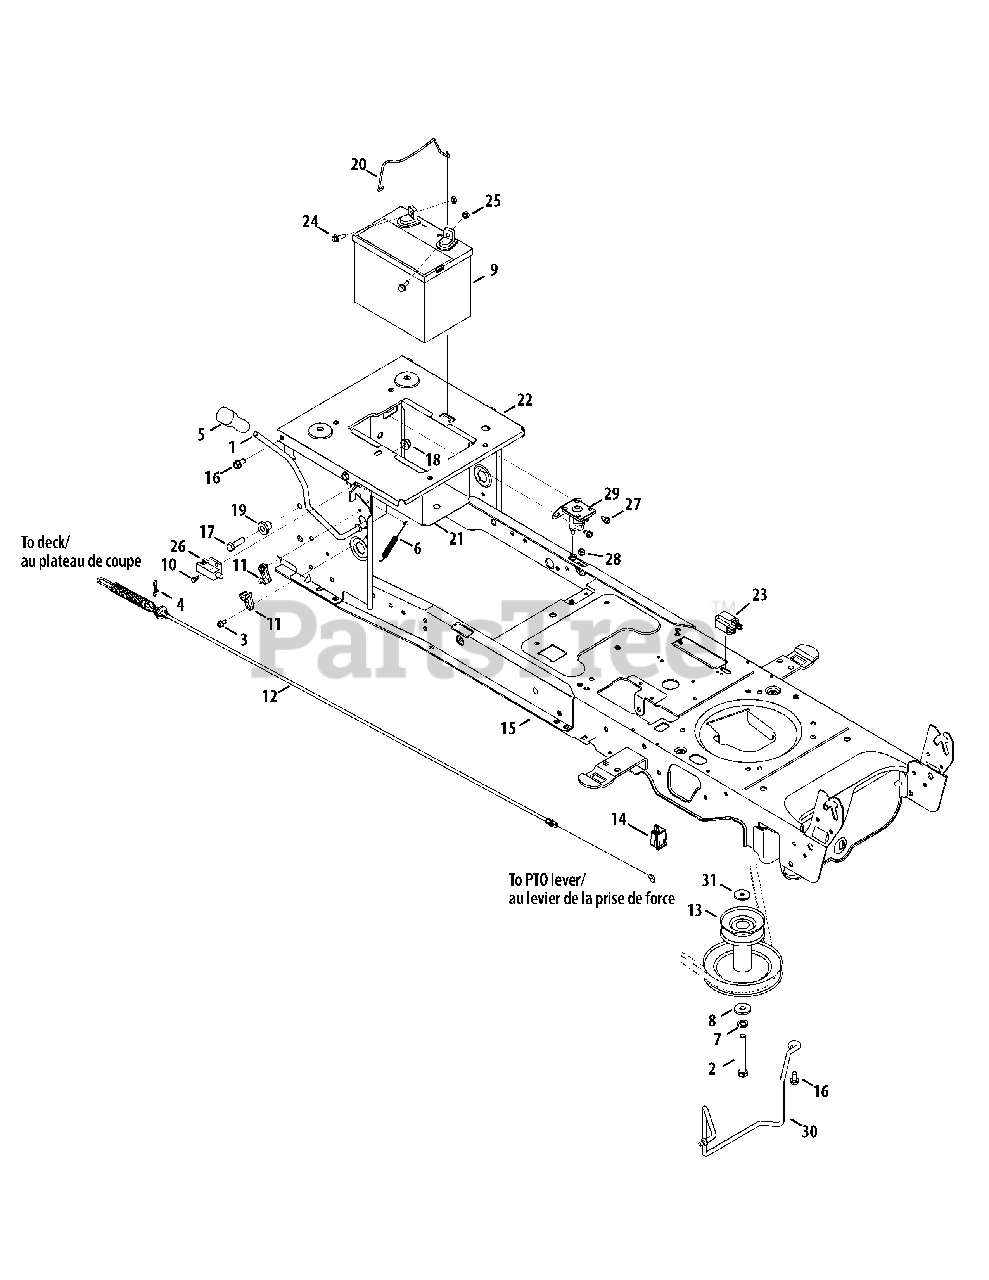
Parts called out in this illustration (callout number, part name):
1	Handle Ass’y , PTO
2	Hex Screw 7/16-20 x 3.5 Gr. 5
3	Hex Wash S-Tapp Screw 1/4-20 x .50
4	Bow-Tie Cotter Pin
5	Handle Grip 3/8
6	Extension Spring .38 Dia. x 5.6
7	Lockwasher 7/16 ID
8	Flat Washer .450 x 1.25 x .164
9	Battery 245 CCA (Dry)
10	Shoulder Screw #10-32 x .50
12	Deck Engagement Cable
13	Engine Pulley 3.39 x 6.12 Dia.
14	Switch, Plunger, snap mount
16	Hex Wash Hd. Tapp Screw. 5/16-18 x .75
17	Hex Bolt 3/8-16 x 1.25
18	Flange Lock-Nut 3/8-16 Gr. F Nylon
19	Shoulder Spacer .38 x 1.0 x .70
20	Battery Retainer Rod
23	Switch, 3-Pole, (NC-NO-NO)-Brake
24	Hex Hd. Flg. Screw. 1/4-20 x .75 Gr. 5
25	Sems Hex Nut 1/4-20
26	Switch, Interlock
27	Hex Wash HD Tapp Screw 1/4-20 x .375
28	Hex L-Flanged Nut 1/4-20 Gr. F Nylon
29	Solenoid
30	Belt Keeper Rod
31	Spacer 1.010 x 1.4 x .825
